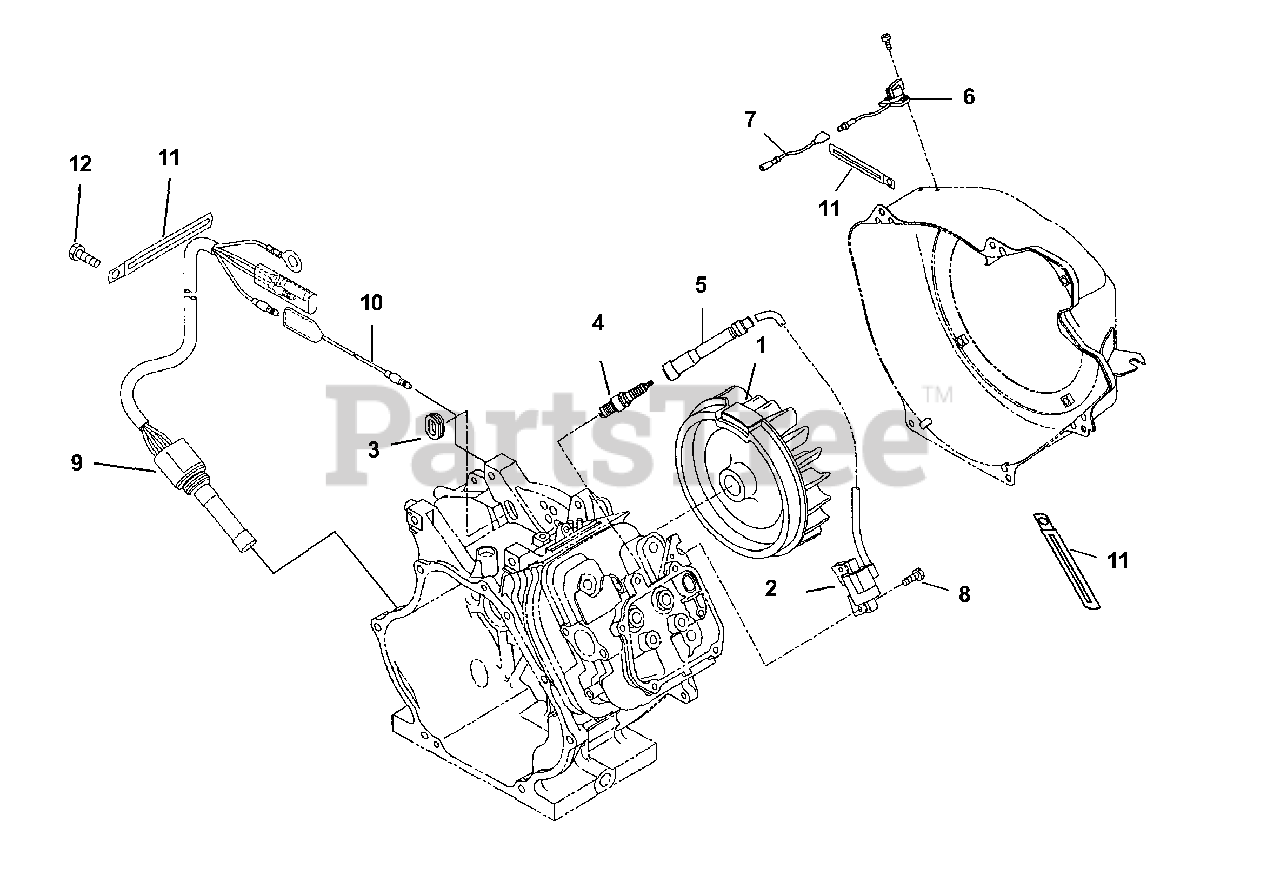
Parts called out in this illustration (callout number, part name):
1	Flywheel
2	Ignition coil cp
4	Spark plug
5	Spark plug cap
8	Bolt and washer
9	Oil sensor
10	Wire 22cp
12	Flange bolt
